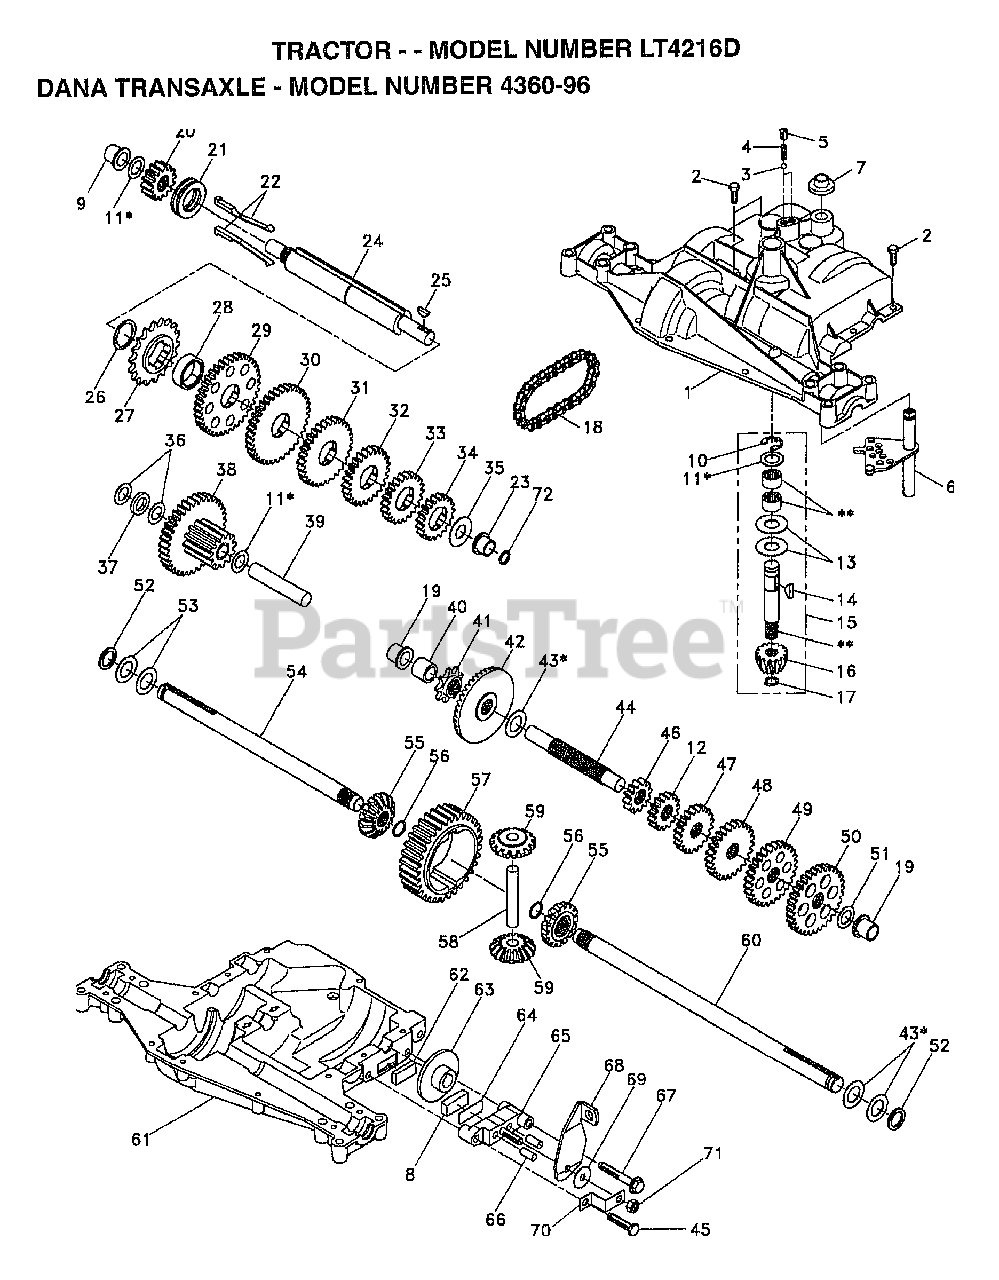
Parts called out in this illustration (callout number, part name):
1	HOUSING UPPER TRN
4	"SPRING, DETENT LT"
5	"SCREW, SET LT"
6	KIT SHIFTER ASM
7	SHIFTER BOOT
8	PUCK T
10	RETAINING RING LT
11	ASM KIT SHIM 4689
12	PLUG.PLASTIC
13	WASHER T
14	KEY WOODRUFF-DANA
17	"RING,RETAINING LT"
18	"CHAIN,24 PTCH LT"
19	BEARING.FLNG.5510
20	GEAR SPUR 14 TTH
21	CLUTCH.COL.5467
22	KIT.ASM.CLUTCH KY
23	BEARING.FLNG.5511
24	SHAFT INTERM DANA
25	WOODRUFF KEY
26	"RING,RETAINING LT"
27	SPROCKET 18T T
28	SPACER YT
29	GEAR SPUR 37 TTH
30	GEAR SPUR 35 TTH
31	GEAR SPUR 30T
32	GEAR 25T LT
33	GEAR SPUR 22 TT
34	SPUR GEAR 19T
35	"WASHER, PLAIN LT"
36	WASHER 025
37	SPACER
38	ASSM GEAR COMB
39	SHAFT IDLER
40	SPACER T
41	SPROCKET 9T LT
43	ASM KIT SHIM
44	SHAFT T
45	"SCREW, TAPPING LT"
46	GEAR SPUR 12 TTH
48	"GEAR, SPUR 25T LT"
49	GEAR 28T T
50	"GEAR, SPUR 31T LT"
51	WASHER 060
52	NEOPRENE WASHER
53	WASHER 031
55	GEAR 15T T
56	"RING,RETAINING LT"
58	SHAFT T
59	GEAR 1ST T
61	HOUSING LOWER TNS
62	PUCK T
63	BRAKE DISC. T
64	SPACER LT
66	PIN T
69	WASHER LT
71	NUT.LOCK.5/16-24
72	SEAL.OIL.DAN.5508
